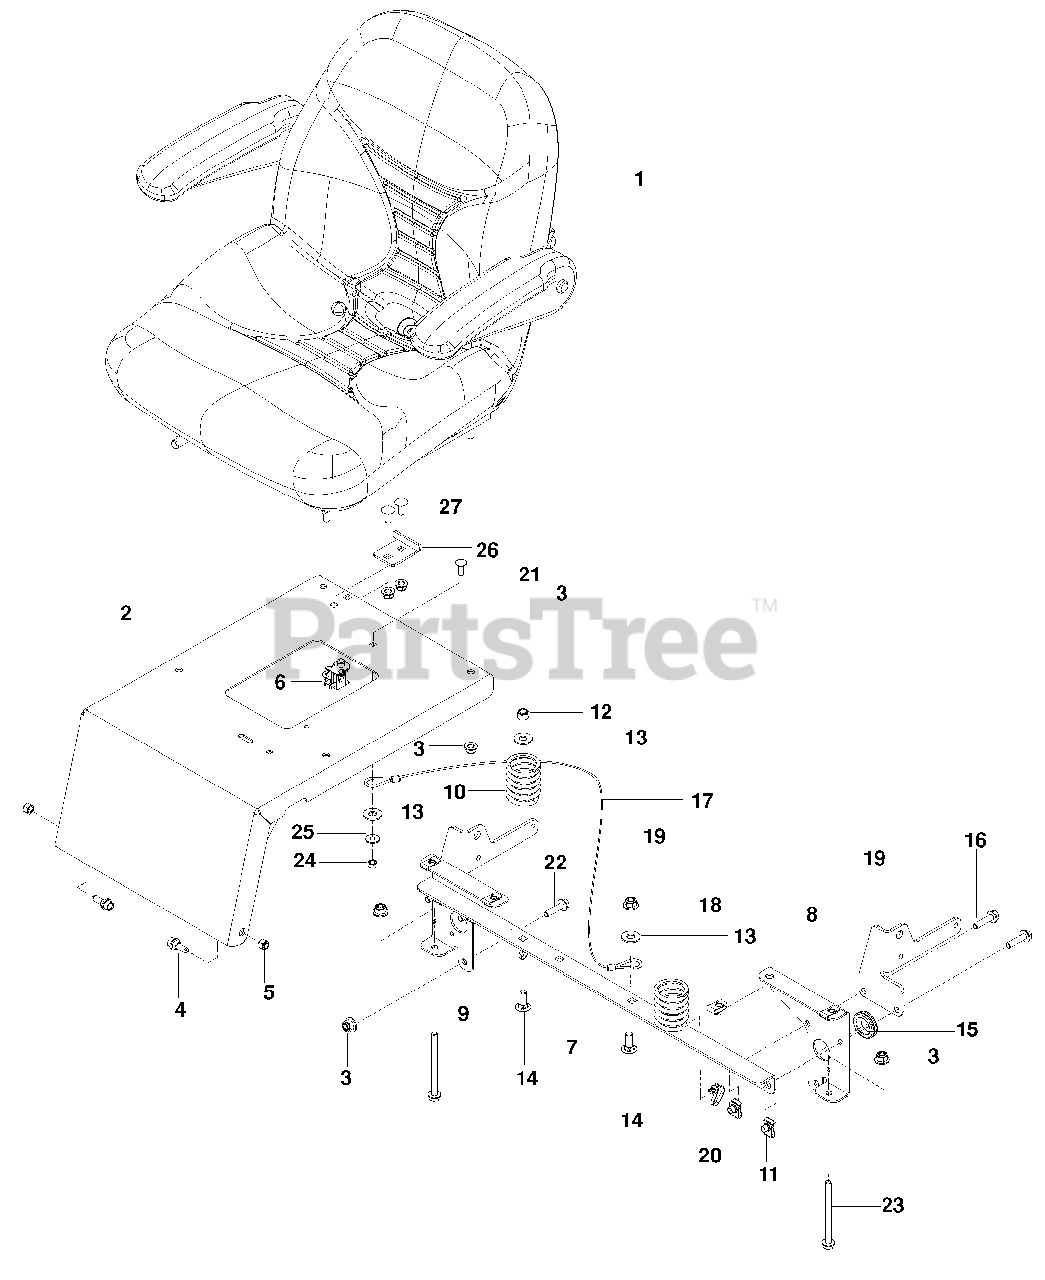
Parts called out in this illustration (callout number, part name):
1	SEAT
2	MOUNT, SEAT w/ DECAL
3	NUT 5/16-18 FLANGE NYLOC
4	BOLT 5/16-18 HEX HD
5	NUT 5/16-18 HEX NYLOC
6	SWITCH, SEAT
7	SUPPORT, SEAT
8	SUPPORT, LT
9	SUPPORT, RT
10	SPRING, SEAT
11	RETAINER, U TYPE 5/16-18
12	NUT 3/8-16 HEX NYLOC
13	WASHER 3/8 FLAT STD
14	BOLT, RD HD 3/8-16 x 1
15	GROMMET RUBBER
16	HHFS 5/16-18 x 1 1/4 TPBLT
17	LANYARD, SEAT
18	NUT 3/8-16 FLG HEX NYLOC
19	MOUNT, SEAT BELT
20	TIE WRAP w/ CLIP
21	RHSNB 1/4-40 x 3/4
22	BOLT, HEX 5/16-18 x 1 THD FM
23	SCREW, HX FLG 5/16-18 x 3 3/4
24	NUT 1/4-20 HEX NYLOC
25	WASHER 1/4 FLAT
26	DECK STOP
27	RHSNB 5/16-18 x 3/4
